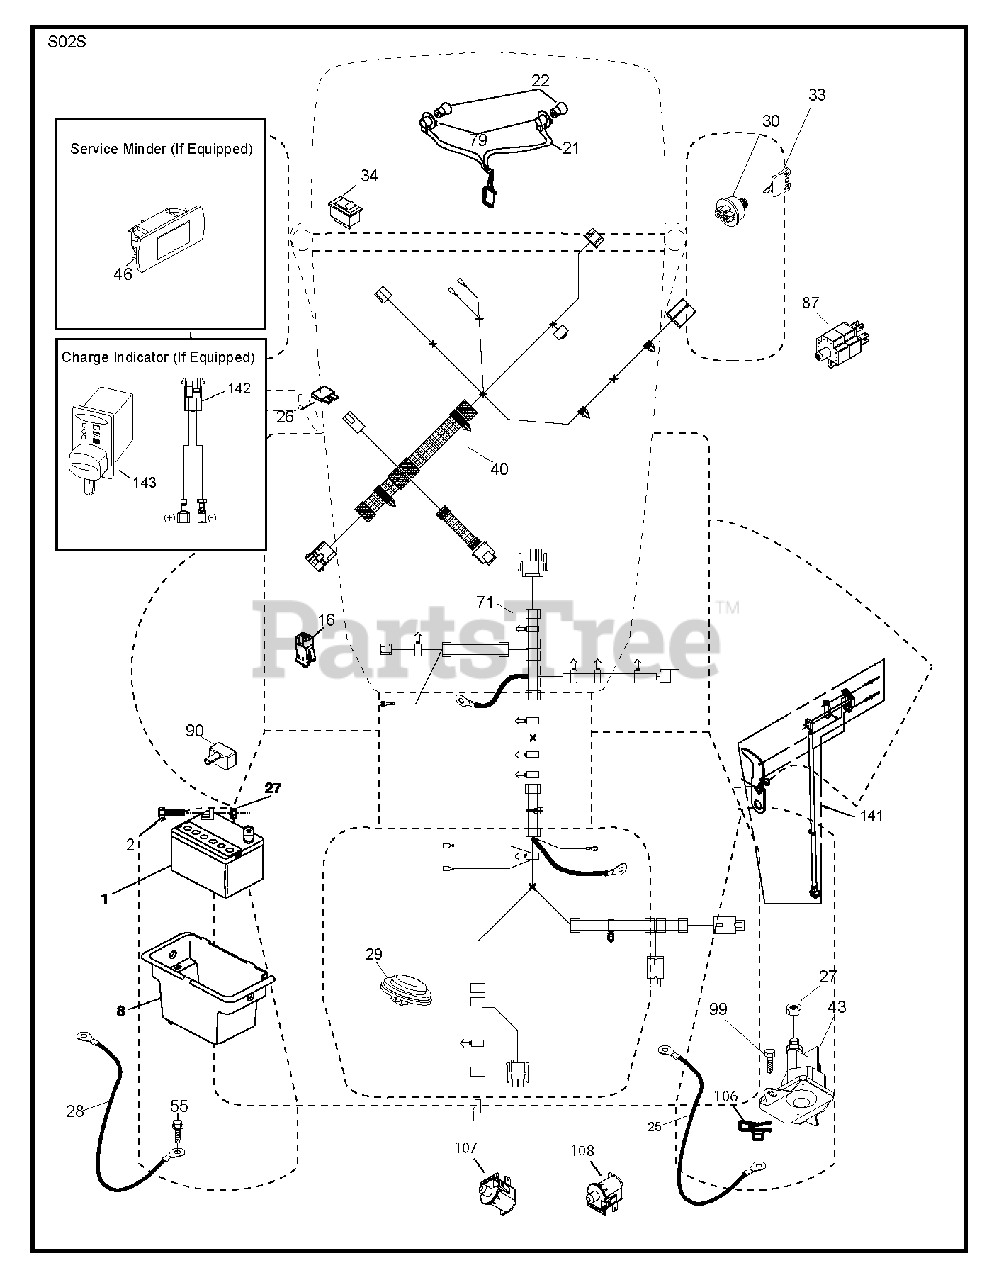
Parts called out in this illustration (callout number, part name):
16	SWITCH INTERLOOK PUSH-IN
21	HARNESS.LIGHT W/4152J BULBS
22	LIGHTBULB
25	CABLE.BATTERY.20.RED.8 AWG
26	FUSE 20AMP
27	NUT
29	SWITCH.SEAT.DELTA.OPC.
30	SWITCH.IGN.DELTA.W.LGH.ROS
33	KEY.CHAIN.BLISTER.PACK.GEN.INT
34	SWITCH LT
43	SOLENOID.W/BRASS.PLUNG
55	SCREW 5/16"
79	BULB HOLDER ASM.
90	COVER.TERMINAL.BATTERY
99	SCREW HEXWSHR 1/4-20X3/4
106	1/4-20 U NUT
108	SWITCH.SNAPMOUNT.NC
141	KIT T2.ROS
